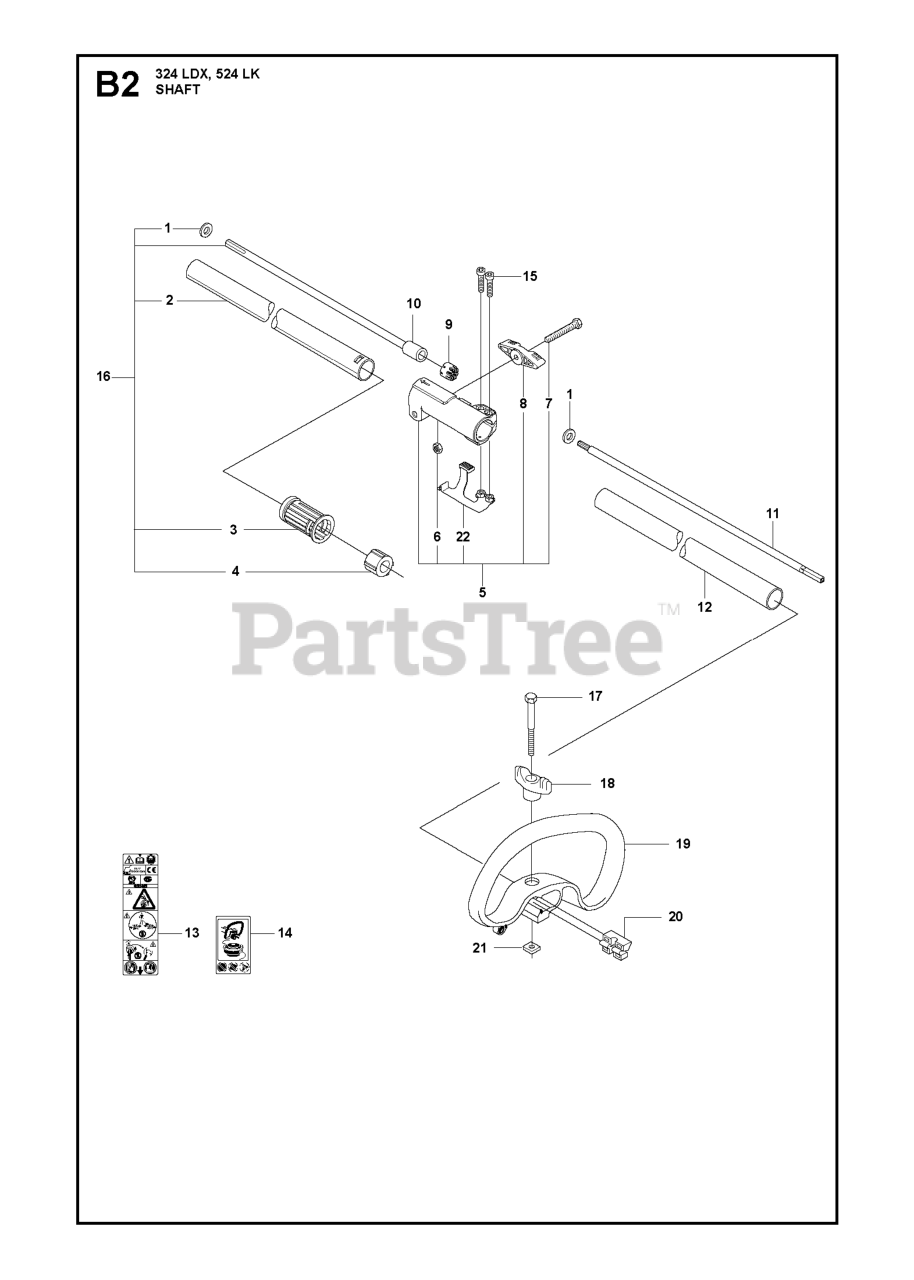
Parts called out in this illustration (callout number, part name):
2	TUBE
5	CLAMPING SLEEVE
7	SCREW
8	KNOB CLAMPING SLEEVE
10	SHAFT
11	DRIVE SHAFT
11	SHAFT UPPER
12	TUBES
13	LABEL WARNING TRIMMERS AND BRU
14	DECAL WARNING "NO BLADES"
17	SCREW M6X50
19	HANDLE, LOOP
20	SPACER PLASTIC
22	LOCKING PLATE ASSY CLAMPING SL
